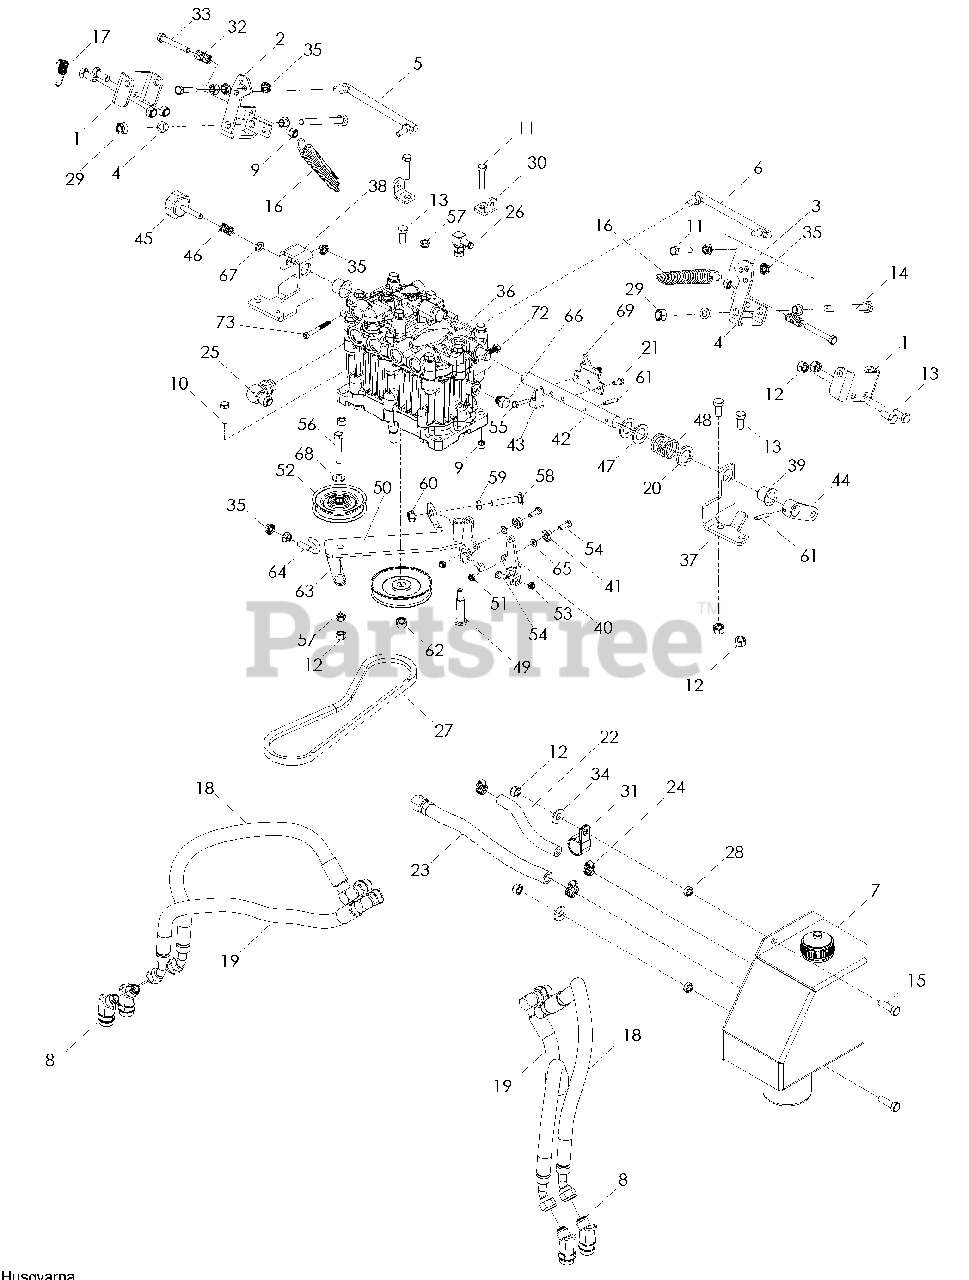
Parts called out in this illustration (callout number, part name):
2	BELLCRANK, RH
3	BELLCRANK, LH
4	BEARING, FLANGE
5	LINK, CONTROL, RH
6	LINK, CONTROL, LH
7	RESERVOIR
8	ELBOW 45DEG STRAIGHT THD
9	NUT 5/16-18 HEX NYLOC
10	HCS 5/16-18 x 1 1/4
11	HCS 5/16-18 x 1 1/2
12	NUT 3/8-16 HEX NYLOC
13	Hcs 3/8-16 x 7/8
14	HCS M10-1.58 x 100 GR 8.8
15	HCS 3/8-16 x 1 1/4
17	SPRING, EXTENSION
20	WASHER, FIBER
21	HCS M6-1.0 x 16MM GR 8.8
22	HOSE, RETURN
23	HOSE, SUCTION
24	CLAMP, HOSE
25	ELBOW 90DEG
26	FITTING 90DEG
28	Nut 3/8-16 Hex Jam
29	NUT, M10-1.5 NYLON RING
30	BRACKET, SPRING
33	HCS 5/16-18 x 2 1/4
34	WASHER 3/8 FLAT
35	NUT 5/16-18 HEX WHIZLK
36	PUMP, DUP10S
37	SUPPORT, CAM LH
38	SUPPORT, CAM RH
39	BEARING, FLANGE
40	ARM, HYDRO
41	BEARING, FOLLOWER
42	SHAFT, CAM
43	CAM, TRACKING
44	ARM, SPEED CONTROL
45	KNOB, ADJUSTMENT
46	SPRING, COMPRESSION
47	WASHER, 20MM
48	SPRING, COMPRESSION
49	PULLEY, PUMP
50	IDLER ARM, BLK
51	SHOULDER BOLT
53	NUT 1/4-20 HEX THIN NYLOC
54	HCS 1/4-20 x 3/4
55	HCS M6-1.0 x 30MM GR 8.8
56	HCS 3/8-16 x 2
57	NUT 3/8-16 HEX JAM NYLOC
58	RHSNB 3/8-16 x 2
59	NUT 3/8-16 HEX JAM
60	NUT 3/8-16 HEX WHIZLK
61	ROLL PIN, 6 MM x 30 MM
62	NUT, M10-1.5 L/H HEX
67	WASHER 5/16 SAE FLAT
68	WASHER, 3/8 SAE FLT
69	PLATE, NEUTRAL STOP
70	NUT M8 x 1.25 NYLOC
71	WASHER 5/16 SLW
72	NUT #10-24 HEX NYLOC
73	SCREW #10-24 SCKT HD
